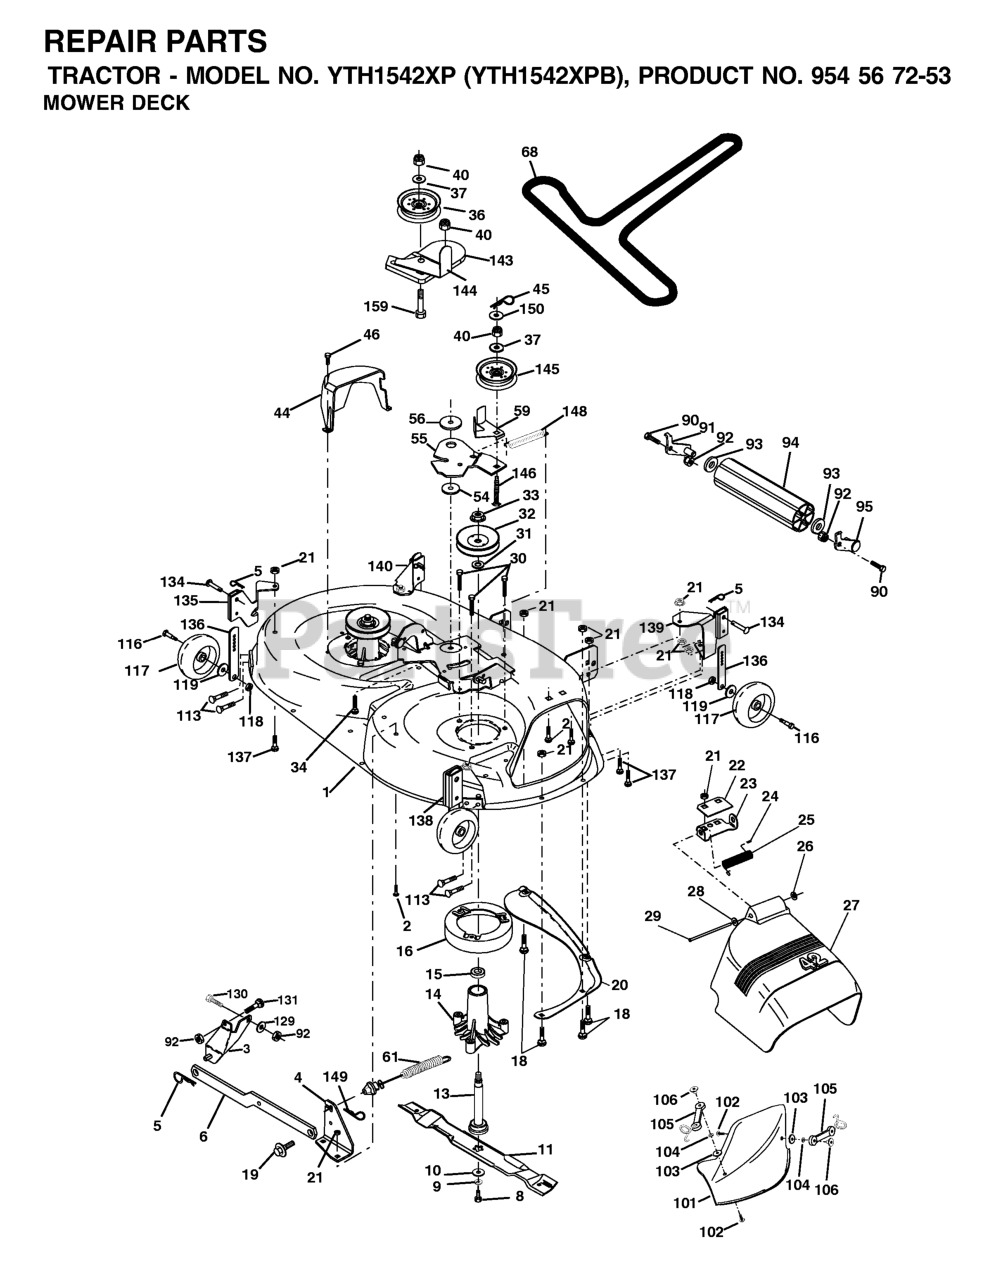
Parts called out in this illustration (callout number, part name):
1	DECK, 42"
2	RP BOLT 5/16-18 X3/4 ZN/YEL GR
3	BRKT ASM SWAY BAR
4	BRACKET SWAY BAR 42" DECK
5	RETAINER-SPRNG RB
6	BAR SWAY DECK
8	BLADE BOLT
9	LOCKWASHER
10	WASHER.BLADE
11	Blade Mower 42" High Perf.
13	SHAFT ASM VENT
14	HOUSING.MANDREL.VENTED (MACHD)
16	STRIPPER.MANDREL.ROUND.BLACK
18	BOLT
19	BOLT SHD 5/16-18
20	BAFFLE.VORTEX
21	LOCKNUT
22	STIFFENER BRACKET
23	DEFLECTOR BRACKET
24	CAP-SLEEVE LT
25	SPRING TORSION
26	NUT PUSH M
27	SHIELD DEFLECTOR
28	Washer 11/32 x 5/8 x 16 Ga SD
29	ROD.HINGE
30	SCREW, WASHER HEAD
31	WASHER
32	PULLEY MANDREL
33	NUT, FLG TOPLOCK 9/16"
36	PULLEY.IDLER.FLAT
37	WASHER
44	GUARD MANDREL LH BLACK
45	RETAINER M
46	SCREW.1/4-20X5/8
54	HARDENED WASHER
55	ARM IDLER 42" MOWER LT/YT
56	SPACER RETAINER
59	GUARD TUV IDLER
61	SPRING EXT ELEC CLUTCH
68	V-BELT PRIMARY 42"
90	BOLT RB
91	BRACKET LH (A)
92	NUT.71038.31-18.HEX.NYLOCK
93	Washer 1 17/32 X 7/8 X 16 Ga
94	NOSE ROLLER
95	BRACKET RH (B)
101	COVER MULCH 42"
102	SCREW
104	LOCKWASHER #10
105	LATCH ASSY
106	WELDNUT
113	SCREW 5/16"
116	BOLT, SHOULDER
117	WHEEL GAGE DONUT
118	LOCKNUT
119	WASHER.5/16.FLAT.STE.STD.
129	WASHER
131	BOLT D
134	RIVET.PIN.HEAD.YELLOW.
135	BRACKET ASM, WHEEL
136	BAR.ADJUST.WHEEL.ANTI.SCALP.BL
137	BOLT.CARR.5/16-18X5/8.SHORT
138	BRACKET.ASM.WHL.GA.R.RH.42".GR
139	BRACKET ASM, WHEEL
140	BRACKET ASM, WHEEL
143	BRACKET, ARM IDLER
144	KEEPER BELT 42" CLUTCH
145	PULLEY.IDLER.FLAT.PLATED
146	BOLT, CARRIAGE IDLER BLACK
148	IDLER RETURN SPRING
149	SPRING.RETAINER.YELLOW.ZINC
